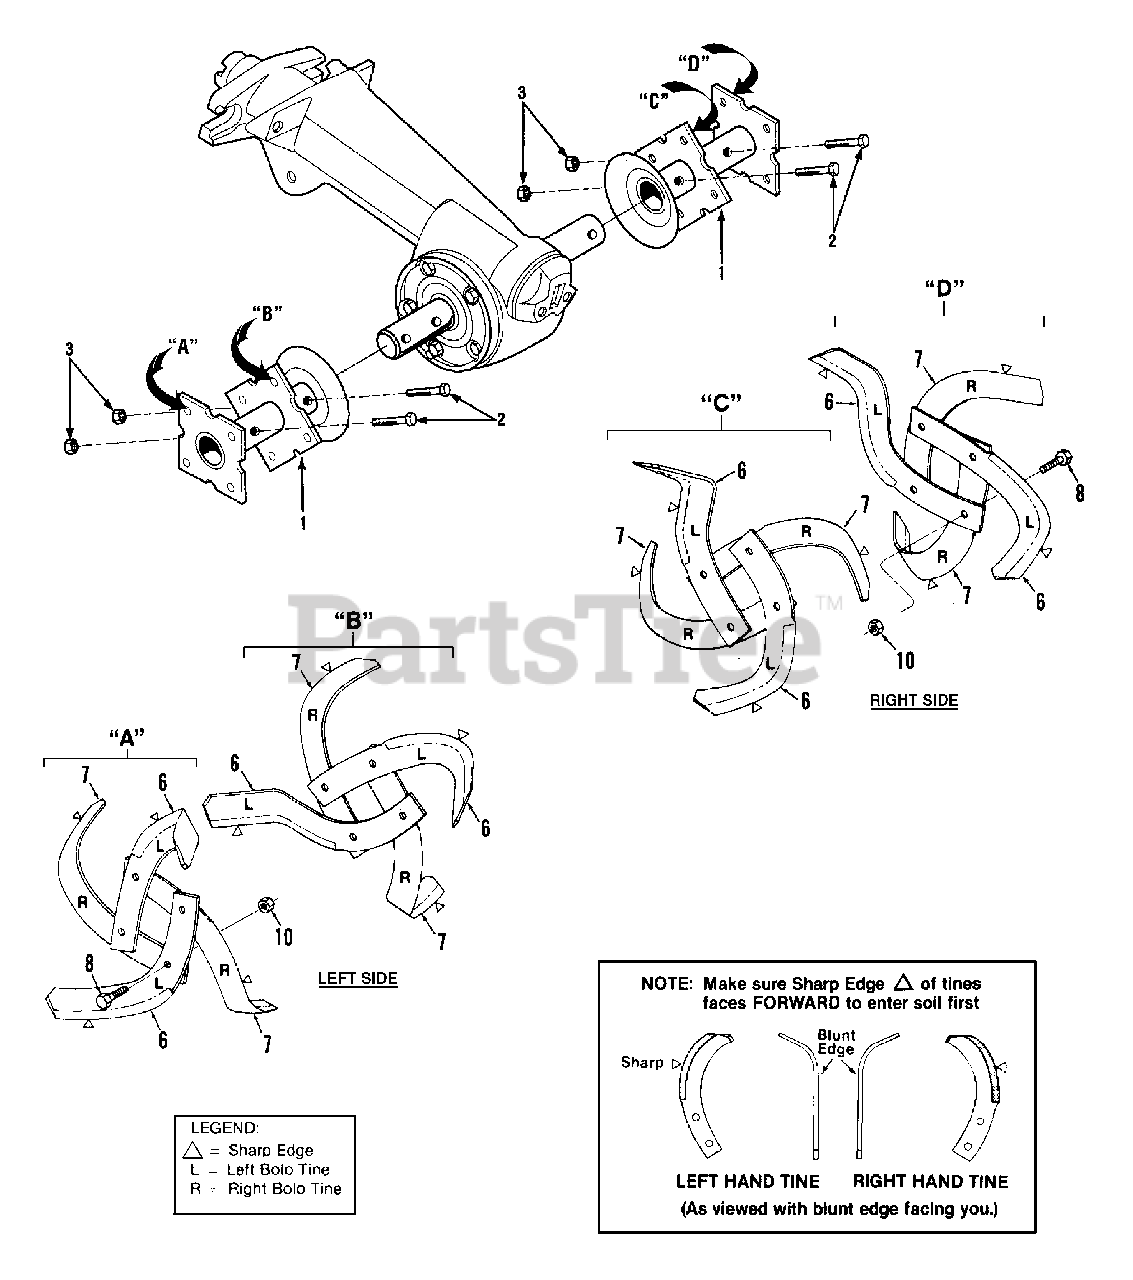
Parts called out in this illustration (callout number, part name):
1	Tine Holder-welded steel, fits left or right sides
2	Bolt-hex hd., 3/8-16 x 2"
3	Locknut-hex, 3/8"-16
6	Bolo Tine-single, left hand
7	Bolo Tine-single, right hand
8	Bolt-hex hd., 3/8-16 x 1"
10	Locknut-hex, 3/8"-16
